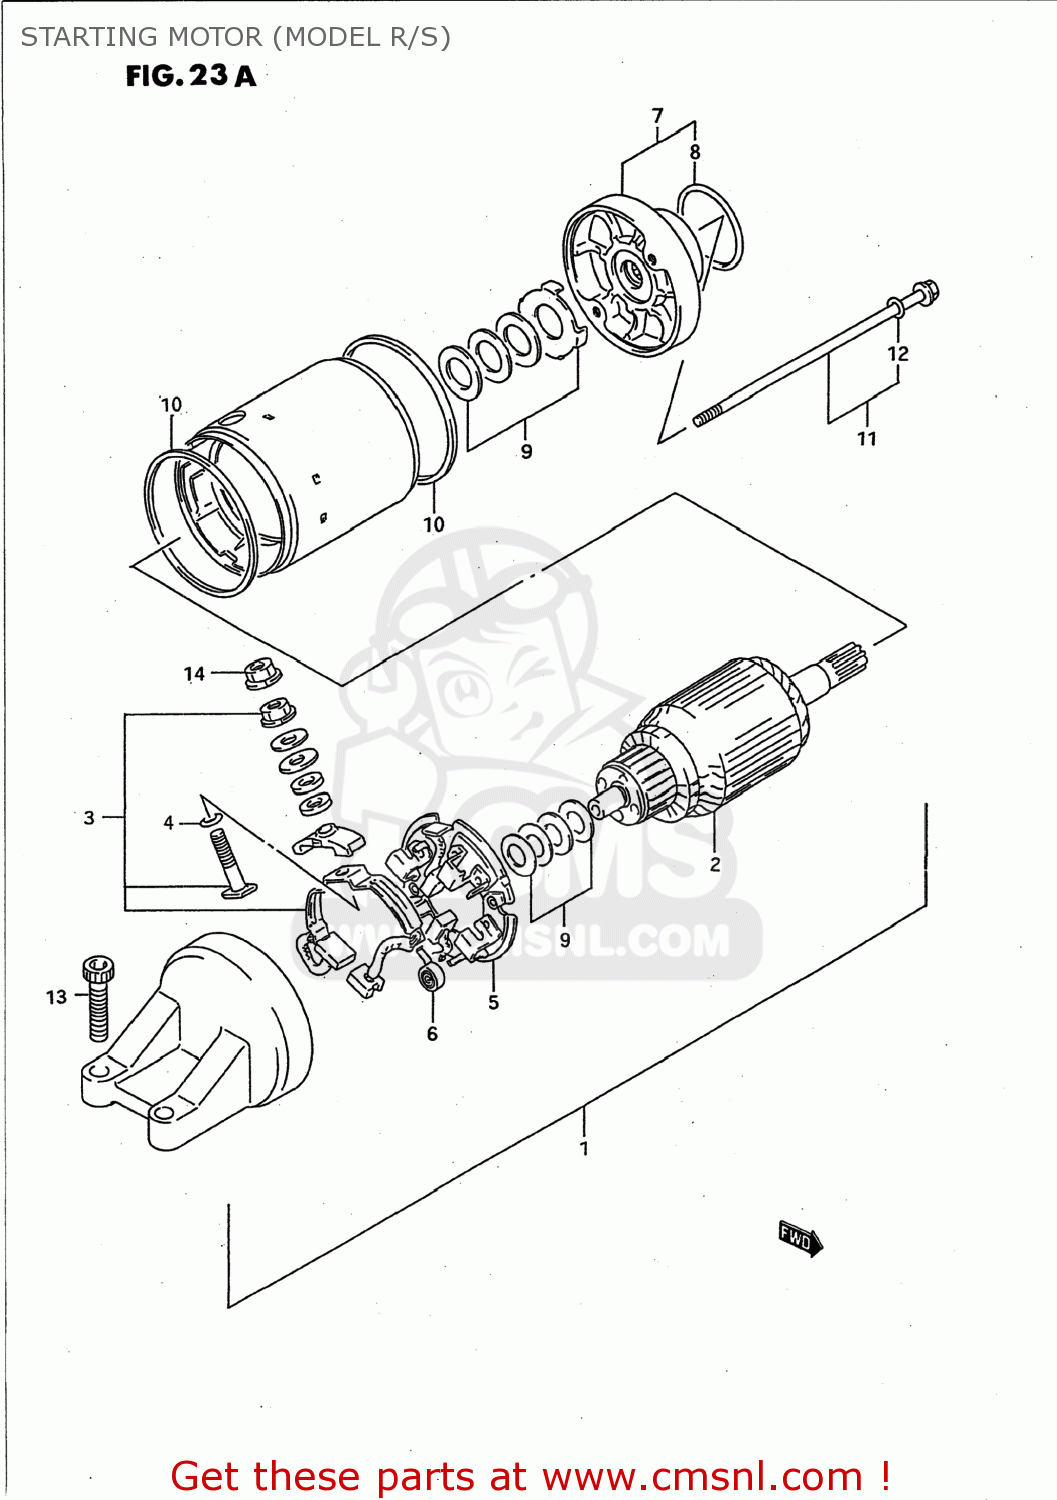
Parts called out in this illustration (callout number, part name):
1	MOTOR ASSEMBLY,STARTING
2	ARMATURE
3	TERMINAL SET,BRUSH,PLUS
4	O RING
5	BRUSH,HOLDER SET
6	SPRING,BRUSH
7	BRACKET ASSEMBLY,FRONT
8	O-RING
9	SHIM SET,STARTING MOTOR
10	O RING
11	BOLT SET,STARTING MOTOR
12	O RING
13	BOLT,OIL PAN
14	NUT
